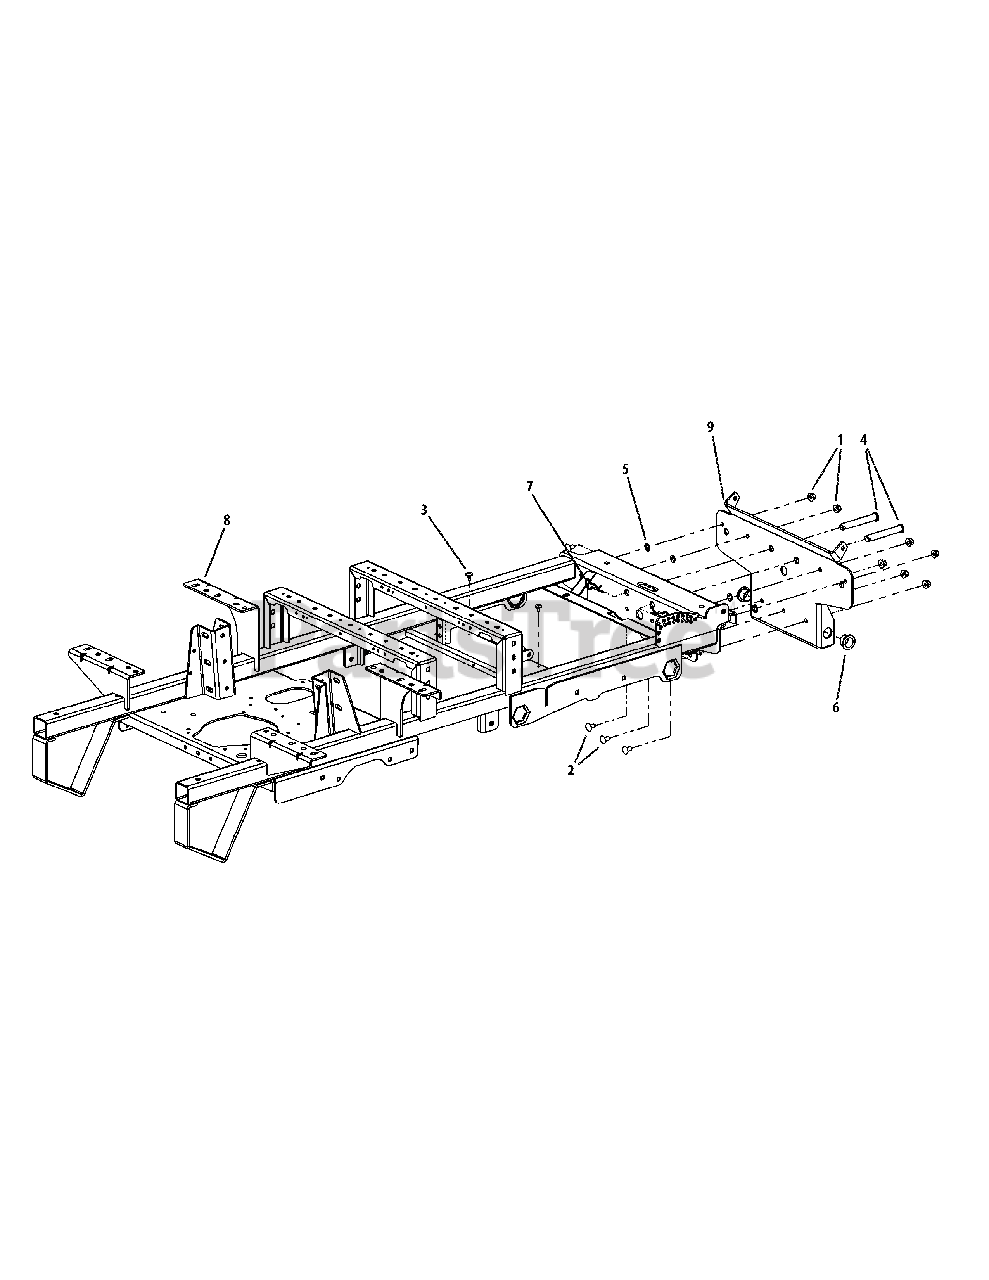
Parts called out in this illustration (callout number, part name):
1	Hex Nut, 3/8-16 Flange Lock
2	Carriage Bolt, 3/8-16 x .75 Long
3	Rubber Bumper, .62 OD x .22 Thick
4	Clevis Pin, .625 Dia x 4.375 Long
5	Push Retainer, 3/8
6	Bronze Bushing, 1.00 ID x 1.50 OD
7	HitchPin, .120 Dia. x 3.0
8	Frame Assembly
9	Bracket Assembly, Frame, Front
